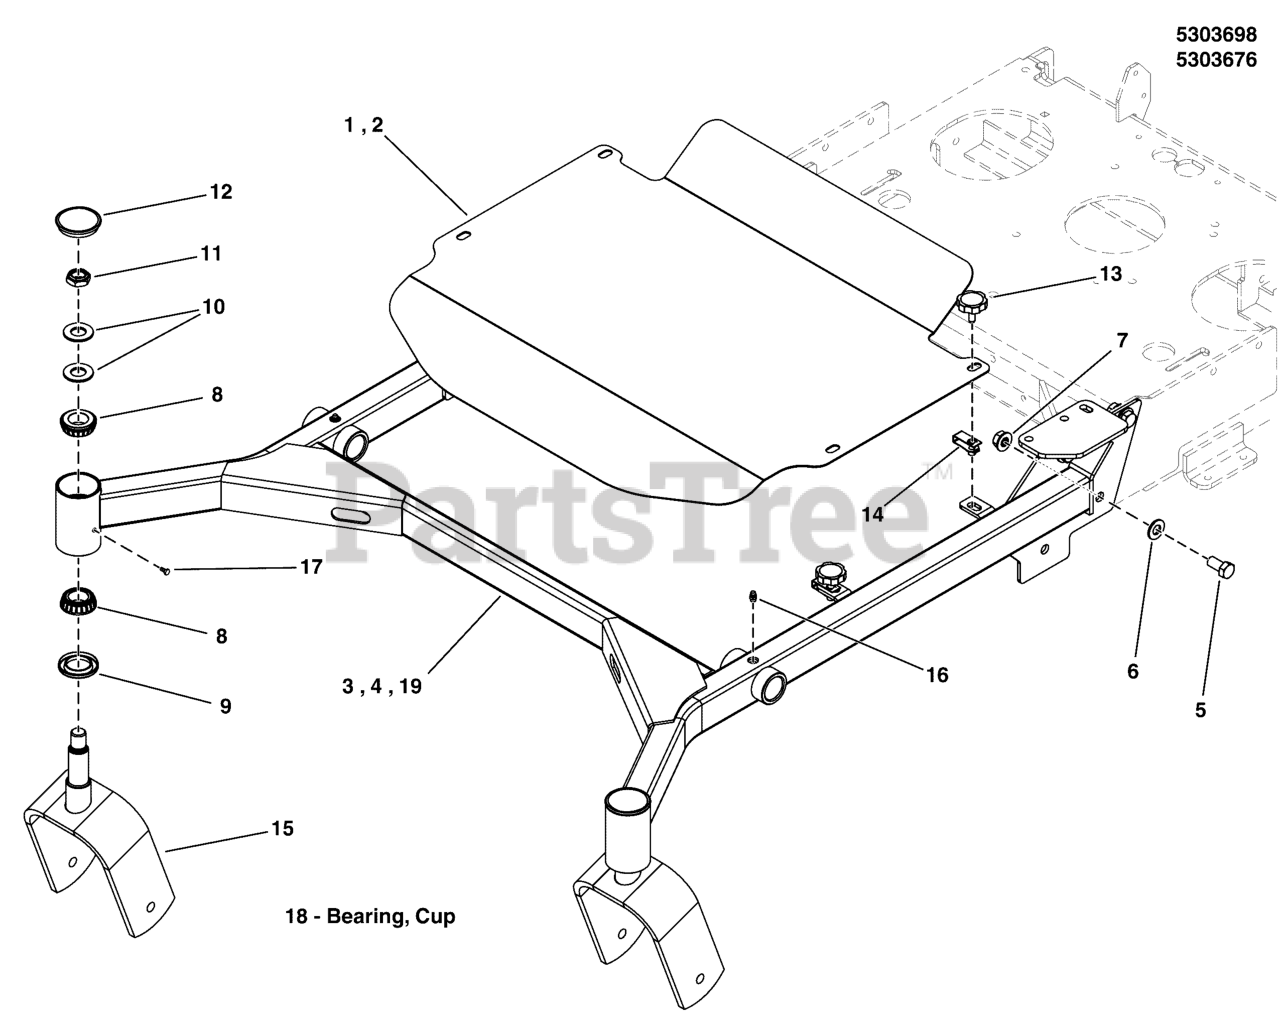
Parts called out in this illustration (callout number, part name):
1	GUARD, WALK, FRONT FRAME, 48-52 - RED
2	GUARD, WALK, FRONT FRAME, 61 - RED
3	WELD, FRONT FRAME, WALK-48-52 - RED
4	WELD, MAIN FRAME, W45, 61 - RED
5	BOLT, 1/2-13 X 1-1/4 GD5 CZ
6	WASHER, 1/2 SAE
7	NUT, Hex Flange, Nylock, 1/2-13
8	BEARING, TAPERED ROLLER, 1"
9	SEAL, GREASE
10	WASHER, BELLEVILLE - 1.500 X .755
11	NUT, 3/4-16, HEX JAM NYLON LOCK
12	CAP, GREASE, LOW PROFILE
13	KNOB, 5/16-18 X 1.00, ROSETTE BLACK
14	BODY CLIP, 5/16-18-7GA MATERIAL
15	WELD., FRONT CASTER YOKES - RED
16	GREASE FITTING, 1/4-28 Straight
17	BOLT, 1/4-28 X 1/2, GD5 YZ
18	CUP, BEARING (SV)
19	WELD, FRONT FRAME, W45, 48/52 - RED
